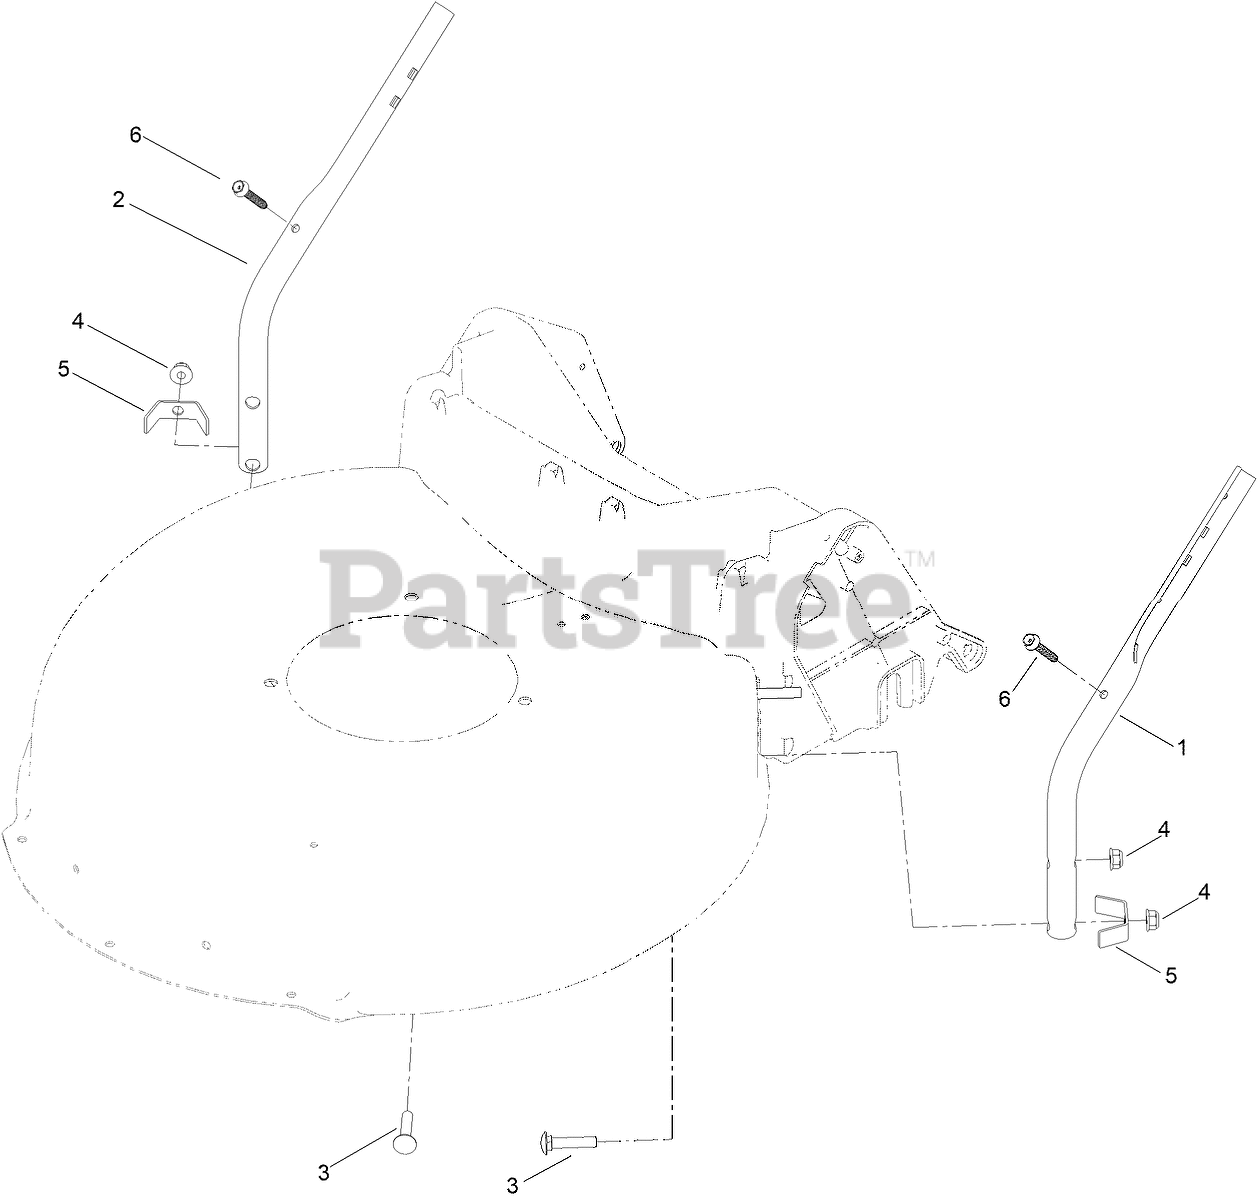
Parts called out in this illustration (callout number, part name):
1	HANDLE-LOWER, LH
2	HANDLE-LOWER, RH
3	SCREW-CARR
4	NUT-HF
5	BRACKET-CHUTE
6	SCREW-FLANGE, SERRATED
